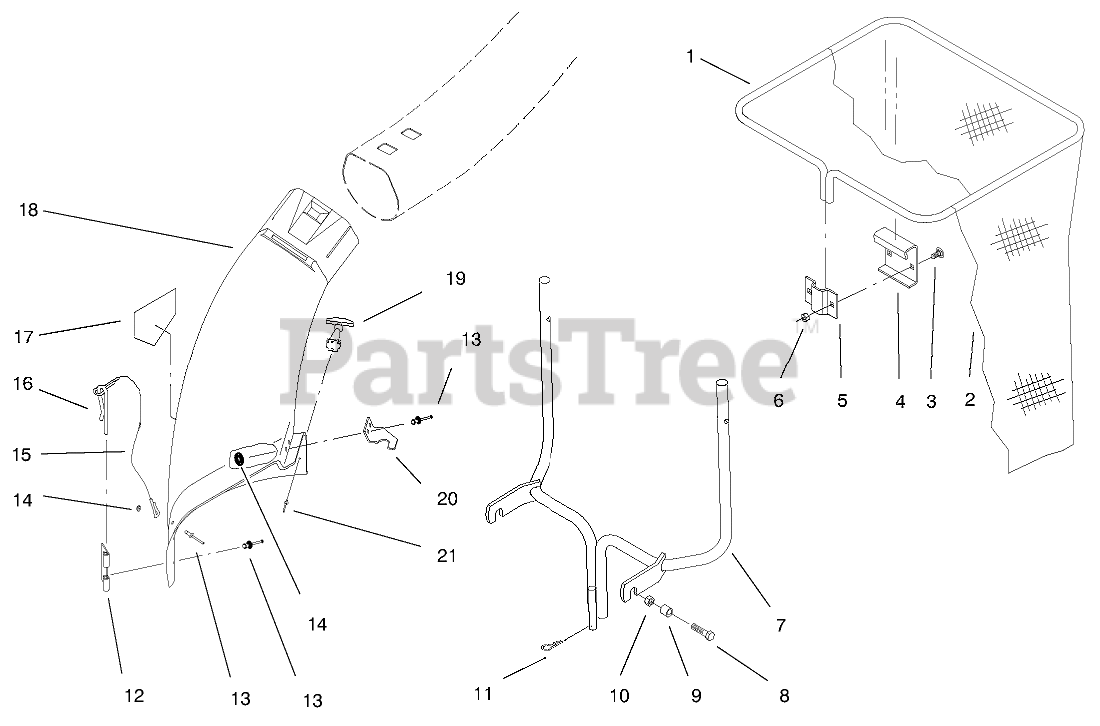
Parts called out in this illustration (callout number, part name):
1	Bag Frame
2	BAG-DEPTH
3	BOLT-CARR
4	Bag Hanger
5	Clamp
6	NUT-LOCK, NI
7	Bracket-Quick Attach
8	SCREW-HH
9	SPACER
10	NUT-LOCK, NI
11	PIN-COTTER, HAIR
12	BRACKET-MOUNTING, CHUTE
13	RIVET-BLIND
14	WASHER-FLAT
15	LANYARD
16	PIN-LOCKING, CHUTE
17	DECAL-DANGER
18	ELBOW-BAGGER, 38 INCH
19	HANDLE ASM
20	LATCH-BAGGER ELBOW
21	RIVET-POP
